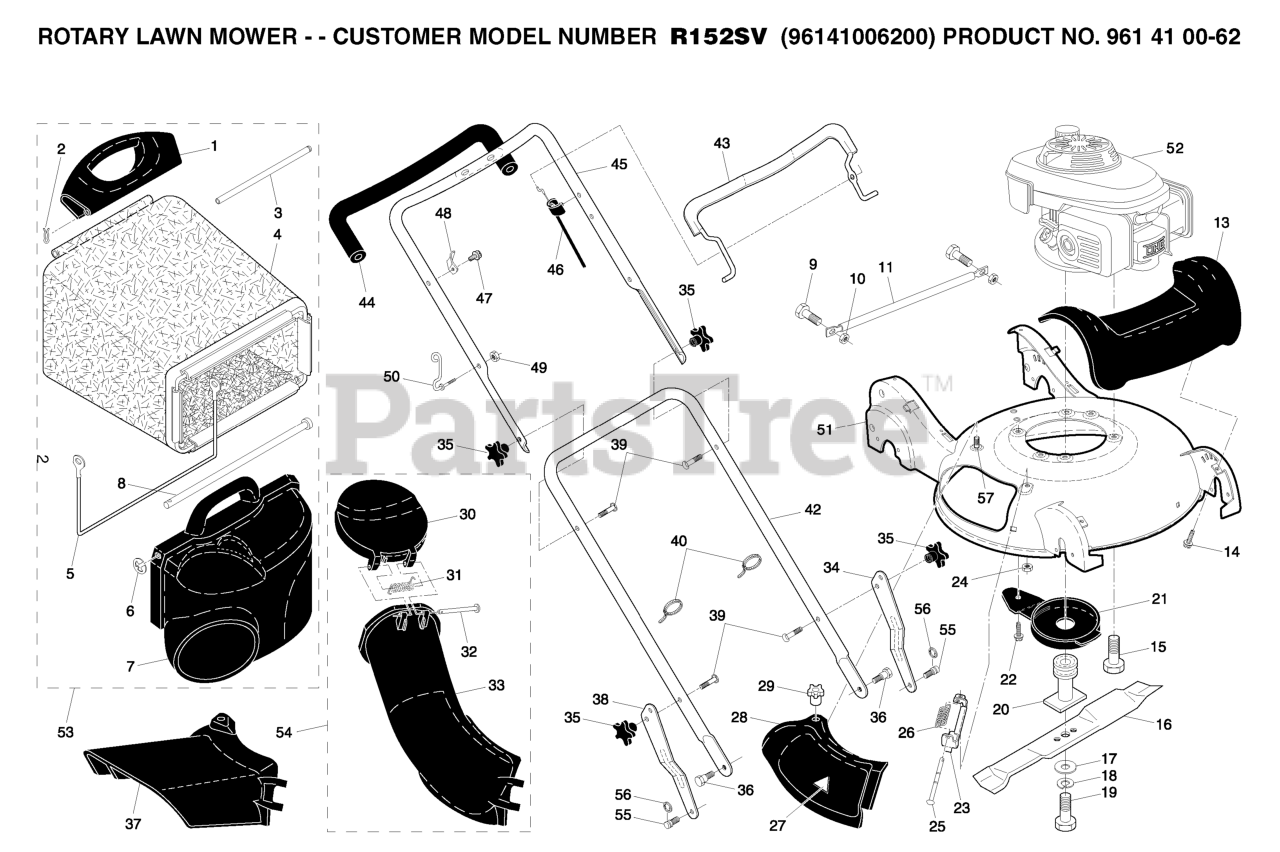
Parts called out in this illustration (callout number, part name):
1	HANDLE.GRASSBAG.REAR.H-GRAY
2	COTTER PIN (3 2)(2 2MC)
3	ROD.REAR.HANDLE.YELLOW
5	FRAME, GRASSBAG
7	DOOR, GRASSBAG
8	ROD, PIVOT
10	LOCKNUT.NYLOC.1/4-20
11	TUBE, REAR SKIRT
13	COVER, FRONT
14	SCREW.HWH.13-16-5.8.BZP
15	BOLT 3/8-16X1-1/8
16	BLADE.21.PUSH
17	WASHER,HARDEN
18	LOCKWASHER
19	BOLT.HD.HEAD.3/8-24X2.50 (2 2)
20	ADAPTER.BLADE
21	DEBRIS SHEILD
22	SCREW 1/4X20
23	BRACKET.ASM.HINGE
24	LOCK NUT
25	ROD.HINGE.1/4"3.82"
26	SPRING.MULCH.DOOR
27	DECAL.INTERNATIONL.CUTFINGER
28	MULCHER DOOR
29	KNOB.MULCH.DOOR
30	CHUTE.DOOR.21.HV.H-GRAY
32	ROD.HINGE.1/4"3.82"
33	DISCHARGE CHUTE PLASTIC
34	ADJUSTMENT BRACKET, LOWER LH
35	KNOB.HANDLE.STAR.HUSQ.GRAY
36	SCREW.5/16X.680.TRIM.H
37	GUARD.CLIP.ON.21.HV.GRAY
38	BRACKET.ADJ.LOWER.HDL.RT.GREY
39	BOLT, HANDLE 5/16-18X1.75
40	TIE GUIDE
42	HANDLE.LOWER.GREY
43	BAIL CONTROL
44	GRIP.HANDLE.FOAM.WIDE.(1 SIDE)
45	HANDLE.ASM.UPPER.W/GRIP
46	CABLE.MZR.50.SNAP-IN
48	BRACKET
49	NUT
50	GUIDE.ROPE.WALK.MOWER
53	Grassbag Assembly, Complete
54	CHUTE.LOWER.ASM.WALK.MOWER
55	STUD.SHOULDER.T45.BZP
56	E-RING 7/16 RE
57	STUD.INSERT
